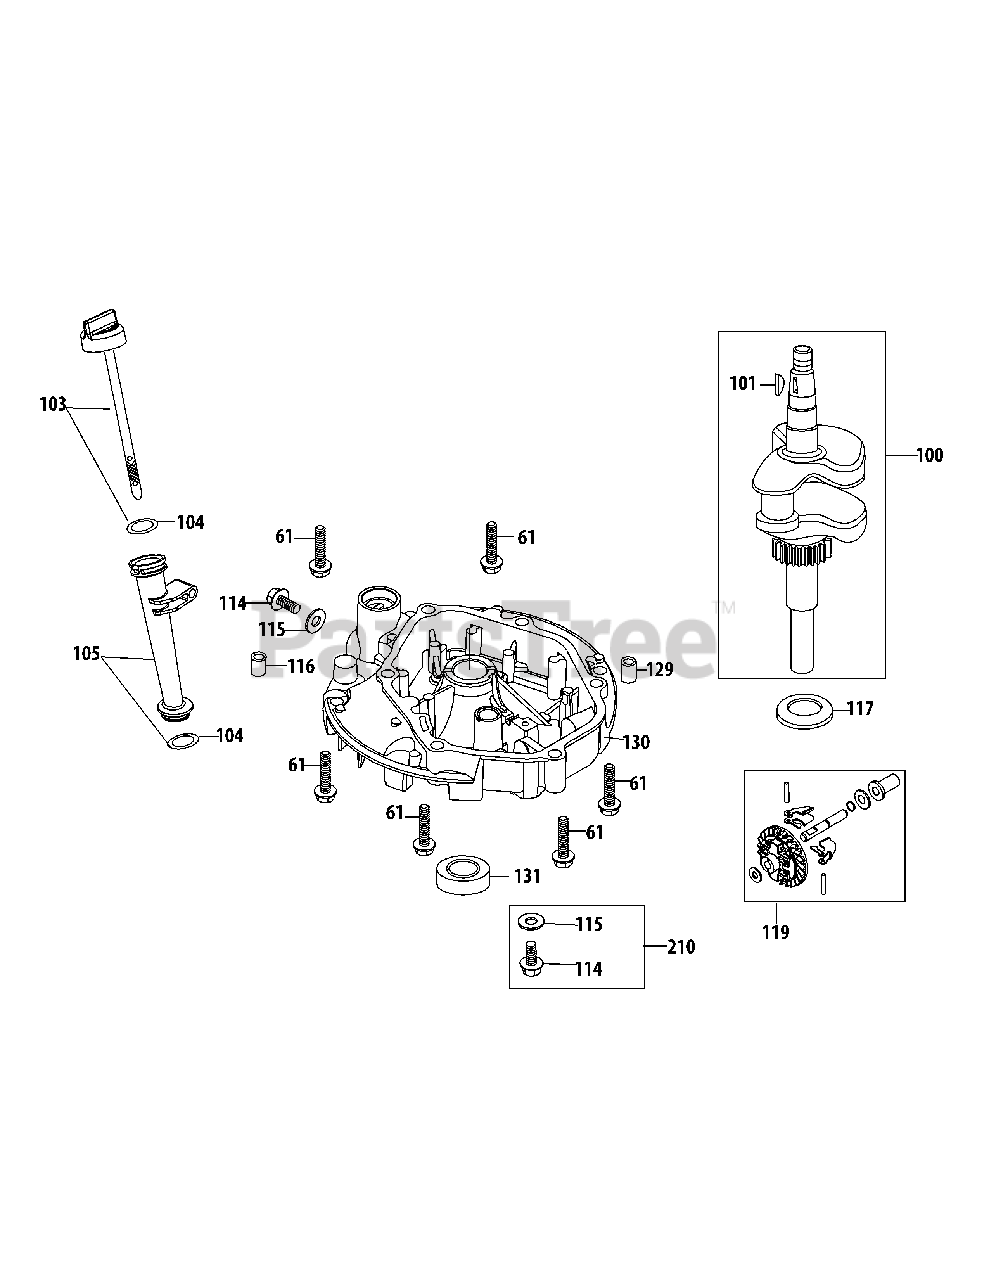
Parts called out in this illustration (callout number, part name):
61	Bolt M8X50
100	Crankshaft Assembly
101	Woodruff Key
103	Dipstick Assembly
104	Dipstick / Oil Fill Tube O-Ring
105	Oil Fill Tube Assemlby
114	Oil Drain Plug
115	Oil Drain Plug Washer
116	Crankcase Cover Dowel Pin 9×14
117	Crankshaft Thrust Washer
119	Governor Gear/Shaft Assembly
129	Crankcase Cover Dowel Pin 7×14
130	Crankcase Cover
131	Lower Crankshaft Seal
210	Oil Drain Plug And Washer Assy
